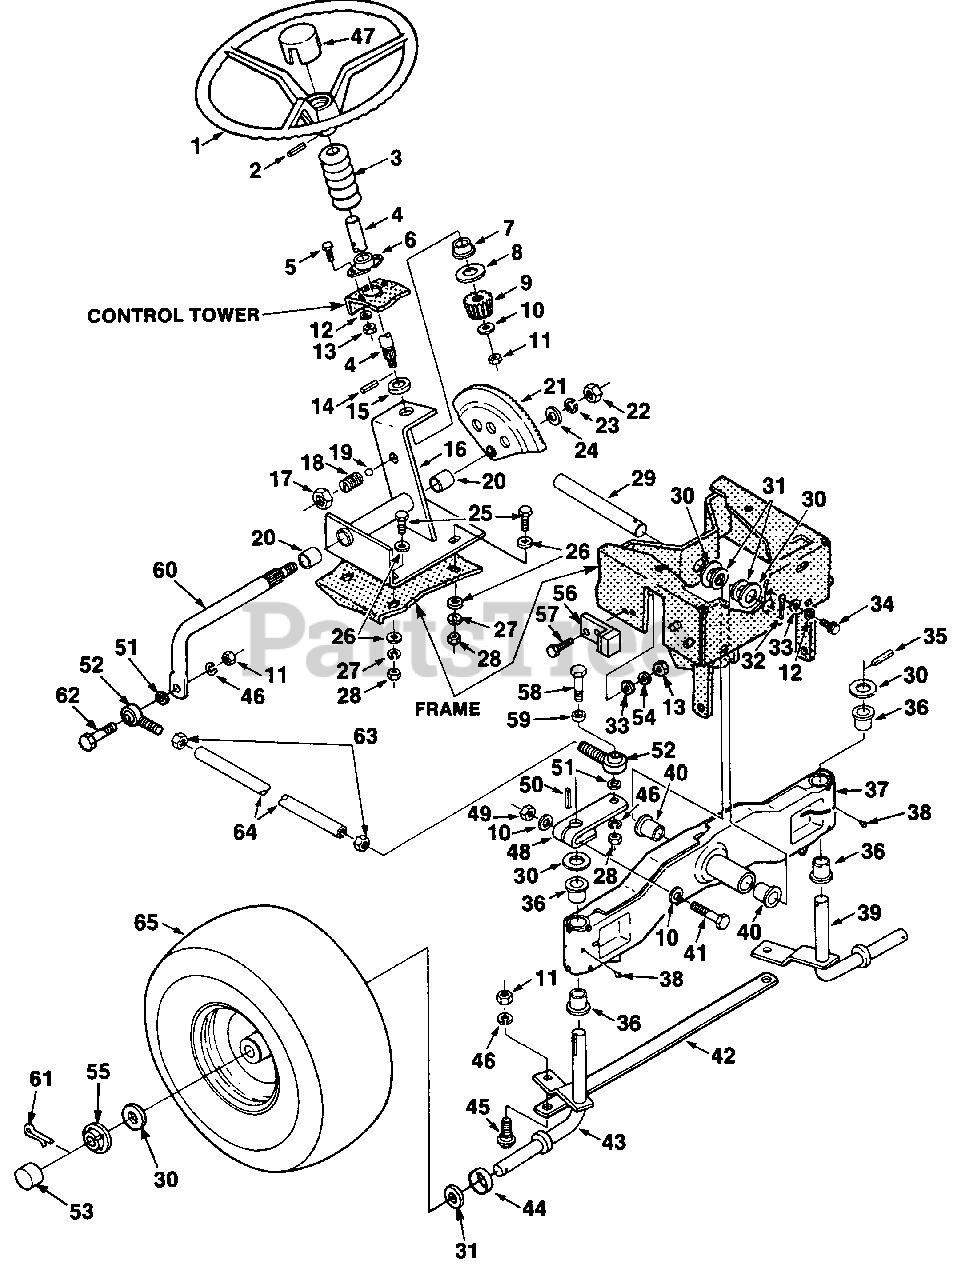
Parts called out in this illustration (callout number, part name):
1	WHEEL- Steering
2	PIN- Roll
3	BELLOW- Steering
4	SHAFT- Steering Wheel
5	SCREW- (1/4-20 x 1/2")
6	BEARING- Steering Shaft
8	WASHER- Front Hub
9	PINION- Steering
11	NUT- Hex (3/8-16)
12	WASHER- Lock (1/4-20)
13	NUT- Hex (1/4-20)
14	PIN- Roll
15	SPACER- Steering
16	SUPPORT- Steering
17	NUT- (5/8-11)
18	SPACER- Steering Gr.
19	BALL- .312 Dia.
21	GEAR- Steering
22	NUT- (1/2-13)
23	WASHER- Lock hvy. (1/2")
24	WASHER- Flat (1/2")
25	SCREW- Hex (5/16-18 x 7/8")
26	WASHER- Flat (5/16")
27	WASHER- Lock (5/16")
28	NUT- Hex (5/16-18)
30	WASHER- Flat (3/4")
31	SPACER- Axle
32	PIN- Cotter (1/4 x 1 1/2")
33	WASHER- Plain (1/4")
34	SCREW- (1/4-20 x 3/4")
36	BUSHING- Spindle
37	AXLE- Front
38	FITTING- Grease
39	SPINDLE- L.H.
41	SCREW- (3/8-16 x 2 1/4")
43	SPINDLE- R.H.
45	BOLT- Tie Bar Mtg.
46	WASHER- Lock (3/8")
47	CAP- Steering Wheel
48	ARM- Steering
49	NUT- Centerlock (3/8-16)
51	SPACER- Balljoint
52	JOINT- Ball
54	WASHER- Lock (1/4")
55	WASHER- Wheel Retaining
56	BRACKET & PAD
57	SCREW- (1/4-20 x 5/8")
58	SCREW- (3/8-16 x 1 3/4")
59	SPACER- Balljoint
60	PITMAN ARM
62	SCREW- (3/8-16 x 1 1/2")
63	NUT- (3/8-24)
64	TUBE- Drag Link
65	RIM & TIRE ASSY.
